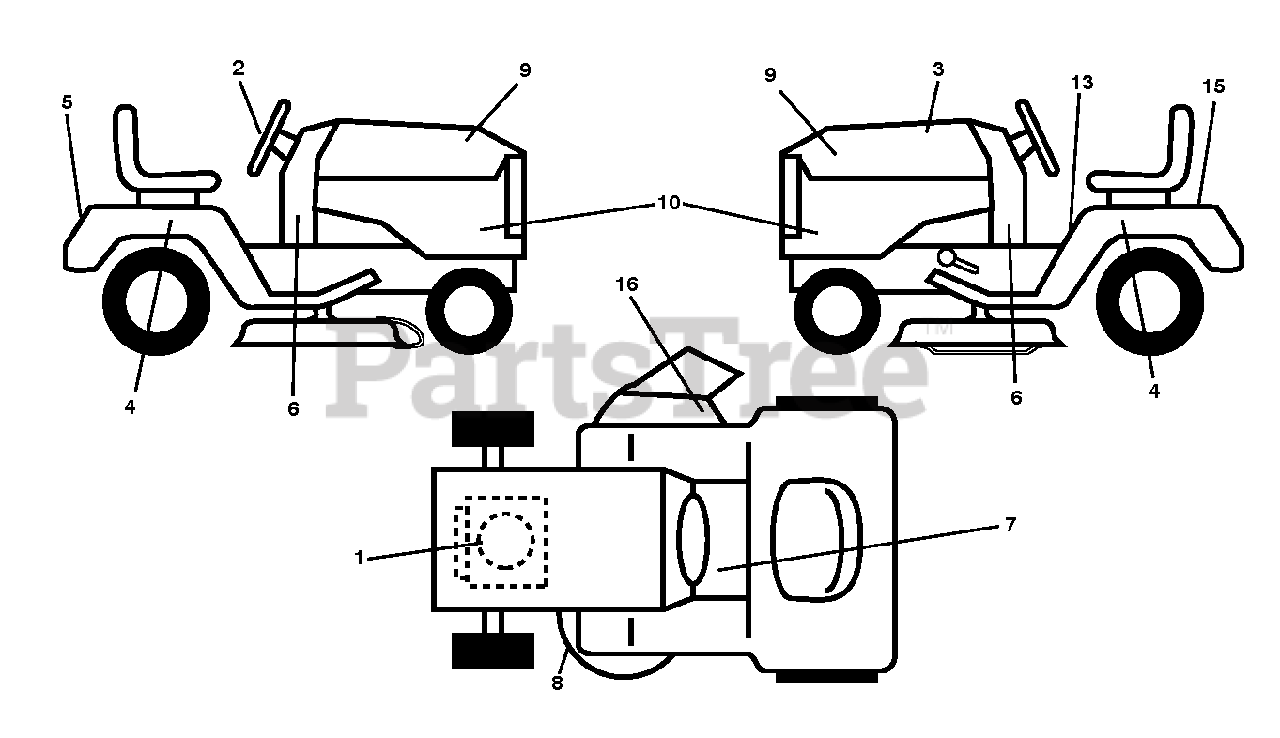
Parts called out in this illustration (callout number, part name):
1	DECAL.ENG.BS.5HP.PB.278978
2	DECAL.STEER.WHEEL.POULAN.PRO
3	DECAL.RPL.PMST.42C.BS.175.STL
4	DECAL.SDFNDR.LTW.SHFTR.SET
5	DECAL.REAR.FNDR.LOGO.POULAN.PR
7	DECAL, WARNING SPARK ARRESTOR
8	DECAL V BELT SCHEMATIC
9	DECAL.HOOD.POULAN.PRO.SET
13	Fender Warning Decal, English
15	DECAL BTRY SYMBOLS
16	DECAL.WARN.KEEP.HAND.AWAY
